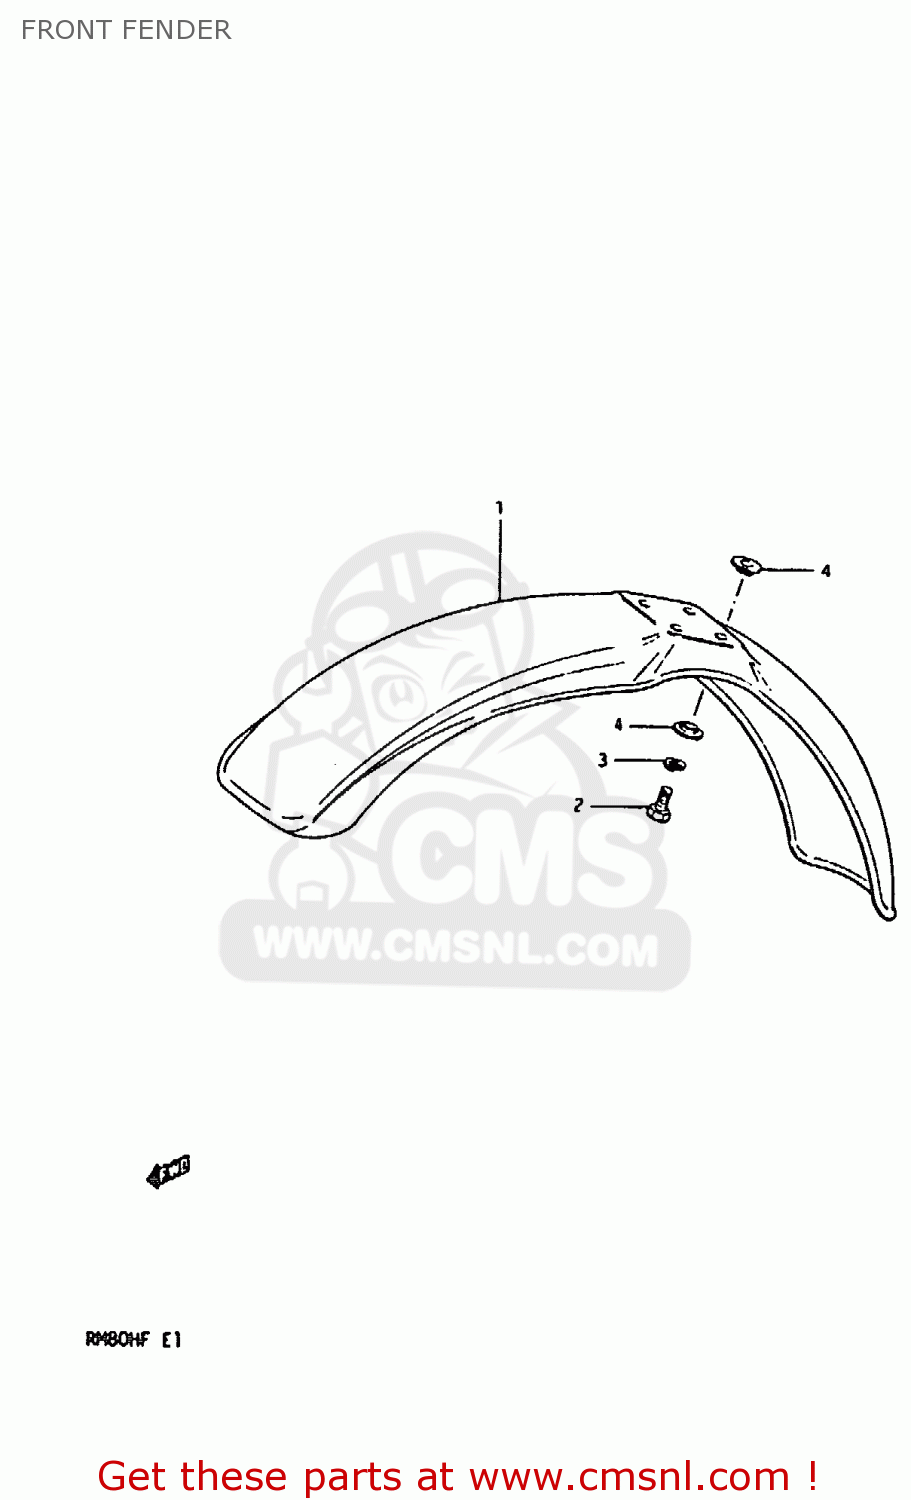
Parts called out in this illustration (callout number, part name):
1	FENDER,FR
2	BOLT, UPPER
3	LOCK WASHER
4	SPACER
